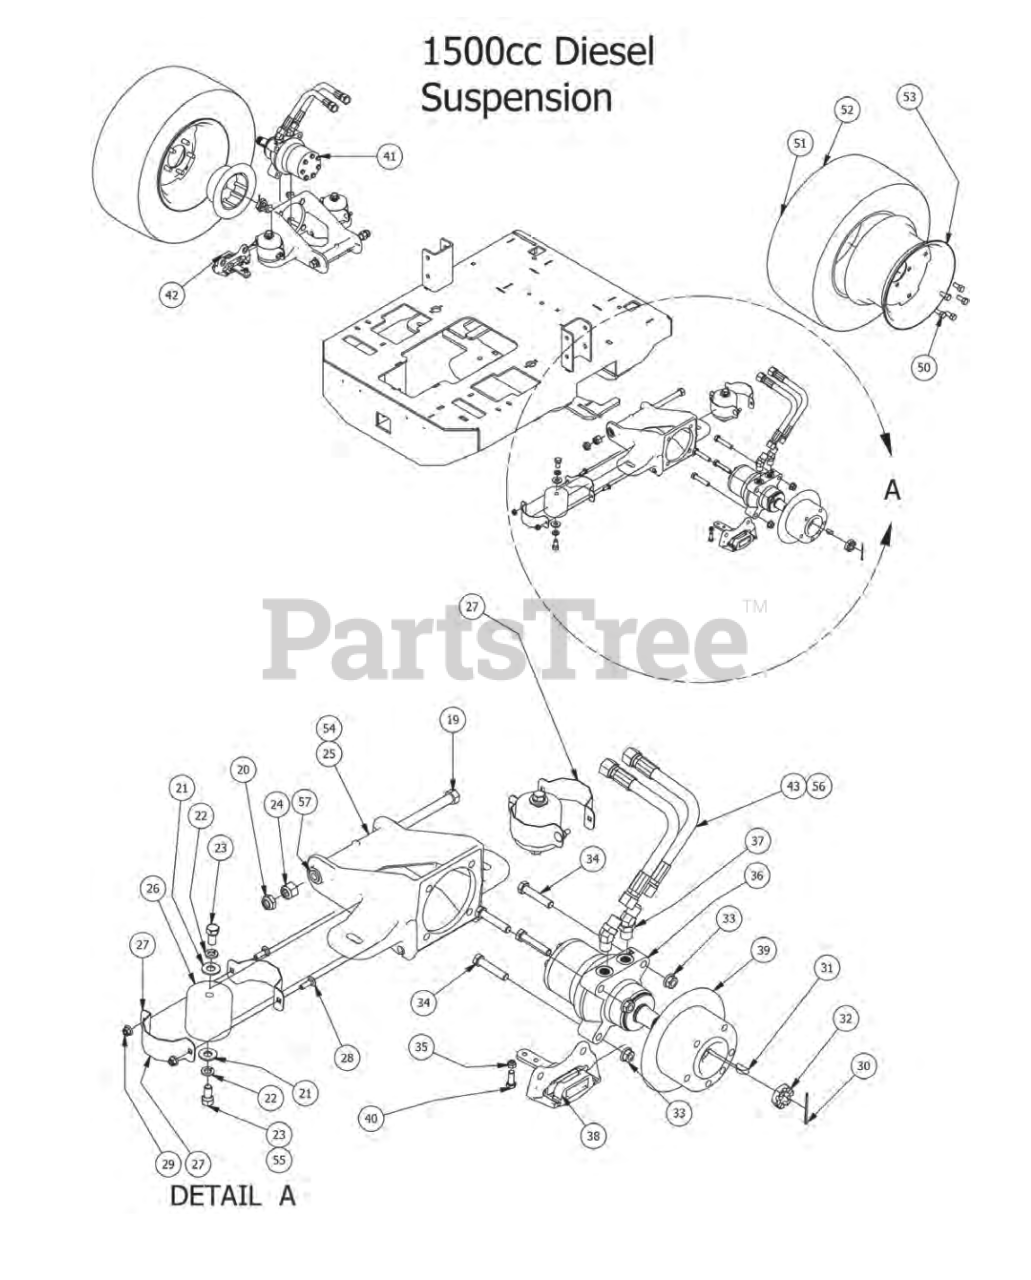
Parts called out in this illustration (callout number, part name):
1	Diesel Back Pump Cover 2008 Bottom
2	Back Cover Hinge Bracket
3	Diesel Back Pump Cover 2008 Top
4	Diesel Hood 4 Cyl
5	5/16" x 1" Carriage Bolt
6	.360 ID Plastic Washer
7	1/4" x 5/8" BS C/S 18-8 SS
8	5/16-18x3/4 carriage bolt
9	5/16" Flange Nut
10	1/4 Nylock Nut
11	5/8 Round Insert
12	5/16" x 1" Bolt
13	5/16-18 Nylock Insert Locknut
14	5/16" Knob
15	5/16" x 1 1/4" Carriage Bolt
16	1/4" x 1 1/2" Self Tapping Screw
17	1/4" Flat Washer
18	8" Rubber Bumper
19	5/8"x10" Hex Bolt (Grade8)
20	5/8" Nylock (1/2 Jam)
21	1/2" Washer (Grade 8)
22	1/2" Lock Washer
23	1/2" x 1" Hex Bolt
24	5/8 Std NC Nylock Nut
25	60 Suspension kit Wheel Motor
26	Vibration Mount-Green Dot
27	Isolator Band Clamp
28	5/16" x 1" Carriage Bolt
29	5/16" Nylon Flange Nut
30	1/8x2-1/4 cotter pin Zinc
31	Woodruff Key
32	1" Castle Nut for Wheel Motor
33	1/2" Flange Nut
34	1/2" x 2 1/2" Hex Bolt
35	5/16-18 Nylock Insert Locknut
36	18cc Parker Wheel Motor- Right
37	45 Degree Wheel Motor Fitting -6802-10-10
38	XP/AOS Right Brake Caliper
39	Brake Disk
40	3/8" x 1" Hex Bolt
41	18cc Parker Wheel Motor- Left
42	XP/AOS Left Brake Caliper
43	26" Hose Assembly with Adaptors
44	5/8" x 2 1/2" Gr5 Hex Bolt (Coarse)
45	5/8 Std NC Nylock Nut
46	5 V Idler Pulley - BCVI-81
47	5/8" x 1/" Collar W/One Set Screw
48	Steel Pump Cover Latch
49	10-24 X 5/8 BS C/S 18-8 SS
50	1/2-20 x 1-1/2 Lug Bolts Zinc
51	26 x 12.00-12 Tire and Orange Wheel Assembly
52	26 x 12.00-12 Tire
53	12 x 10.5 Wheel AOS Rear
54	72 Suspension Kit Wheel Motor
55	1/2-13 1-1/4 Hex bolt Only On 60" Suspension Kit Wheel Motor
56	26" Hose Only
57	Brass Bushing
58	10-24 Nylock Locknut
